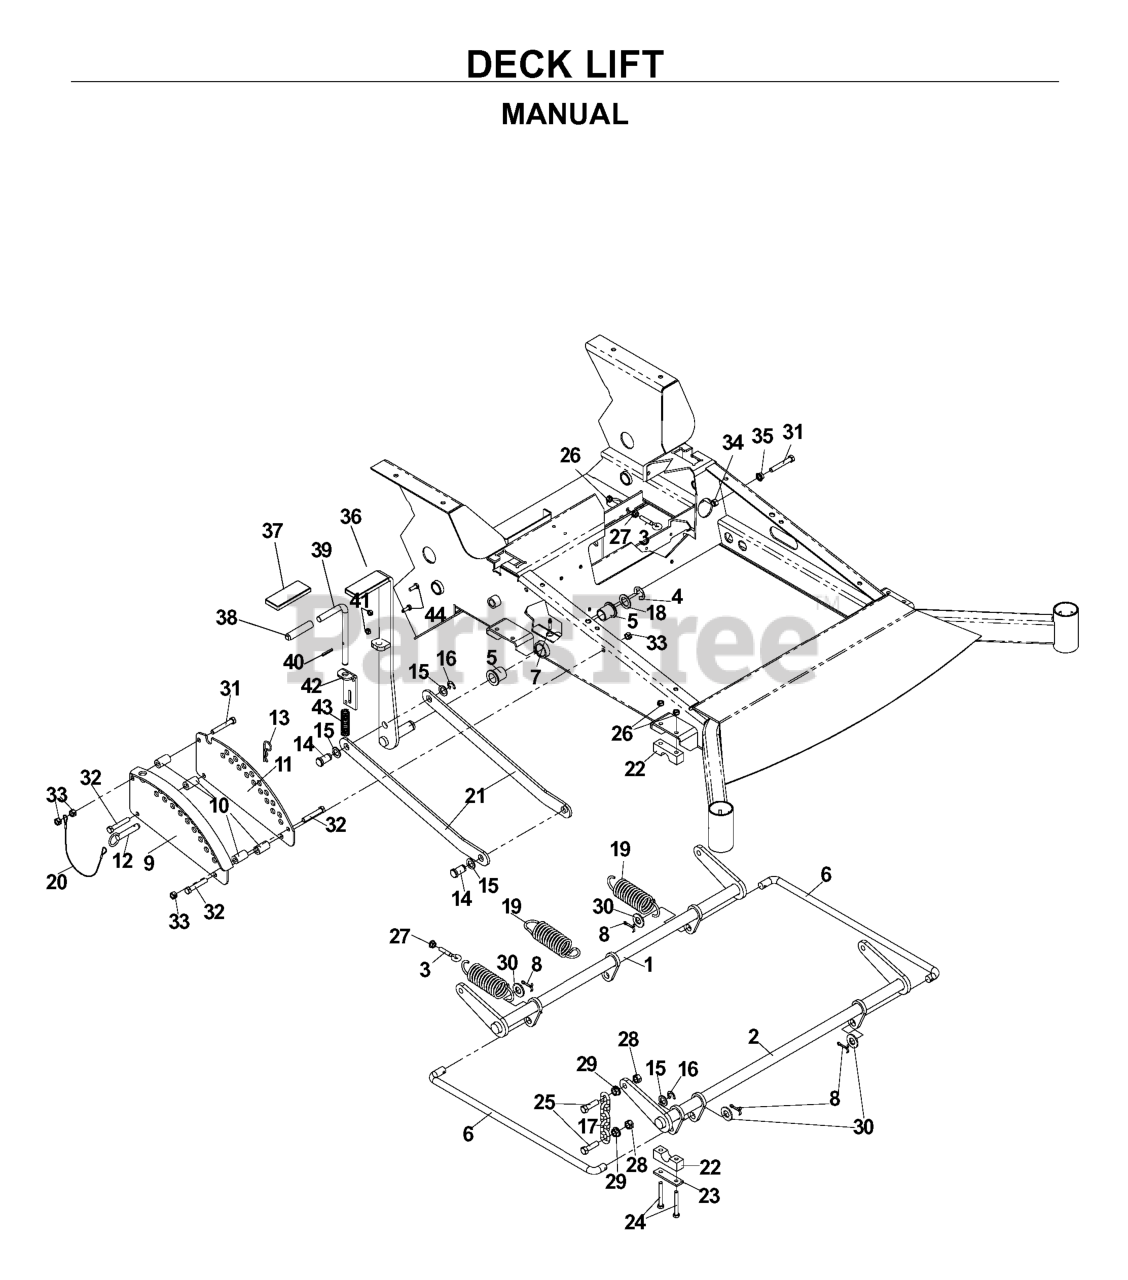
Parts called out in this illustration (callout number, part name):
1	SHAFT LIFT REAR
2	LIFT SHAFT
3	EYEBOLT, RH
4	E-RING 7/8
5	BUSHING, FLANGED
6	CONNECTING LINK
7	GREASE ZERK LONG
8	COTTER PIN
9	ADJ. PLATE WLDMNT
10	DECK LIFT SPACER
11	ADJ. PLATE PAINTED
13	HAIRPIN #4
14	CLEVIS PIN
16	E-RING 5/8
17	LIFT CHAIN
18	BSHG .875 X 1.375 X .074 ZD
19	DECK LIFT SPRING
21	LIFT LINKAGE,PAINTED
22	PILLOW BLOCK
23	REINFORCEMENT BAR
24	BOLT 5/16C X 2 1/2
25	HCS 7/16C X 1 1/2
26	NUT 5/16C CENTERLOCK
27	NUT 5/16C WHIZ
28	NUT 7/16C CENTERLOCK
29	NUT 7/16C WHIZ
30	WASHER 5/8 FLAT
31	HCS 3/8C X 2 1/2
32	HCS 3/8C X 2 1/4
33	NUT 3/8C CENTERBLOCK
34	NUT 3/8-16 NYLOC
35	NUT 3/8C WHIZ
36	LIFT LEVER WELDMENT
41	NUT 1/4C CENTER LOCK
42	PIN MT, UPPER
44	HCS 1/4C X 3/4 HCS
